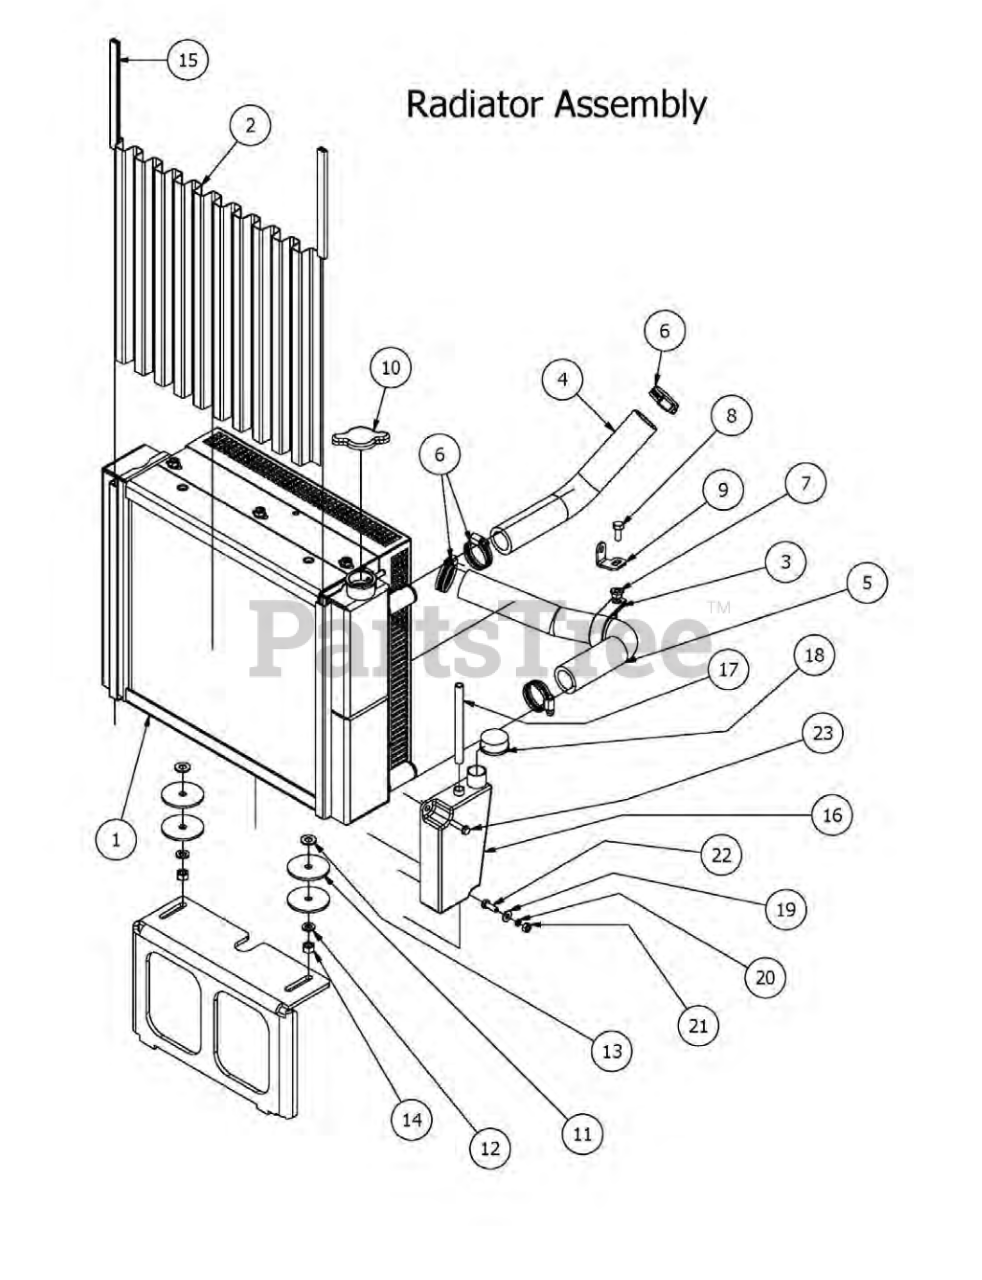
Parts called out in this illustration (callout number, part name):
1	Radiator- Diesel
2	Radiator Screen-Diesel
3	Diesel Clamp 1 3/4" Vinyl
4	Top Radiator Hose for Diesel
5	Bottom Radiator Hose for Diesel
6	1 1/8" Hose Clamp
7	5/16" Nylon Flange Nut
8	5/16" x 1" Hex Bolt
9	Diesel Radiator Hose Clamp Bracket
10	Radiator cap
11	3/8 x 2-1/4 OD Fibre Washer
12	3/8" Lock Washer
13	3/8" Flat Washer
14	3/8" Hex Nut
15	Rubber Trim
16	overflow Reservoir- 28/35Hp Diesel
17	5/16 Clear Hose
18	Reservoir Tank Cap-Overflow
19	1/4" Flat Washer
20	1/4" Lock Washer
21	1/4" Hex Nut
22	1/4" x 3/4" Hex Bolt
23	1/4 x 1 Hex Head tek screw
